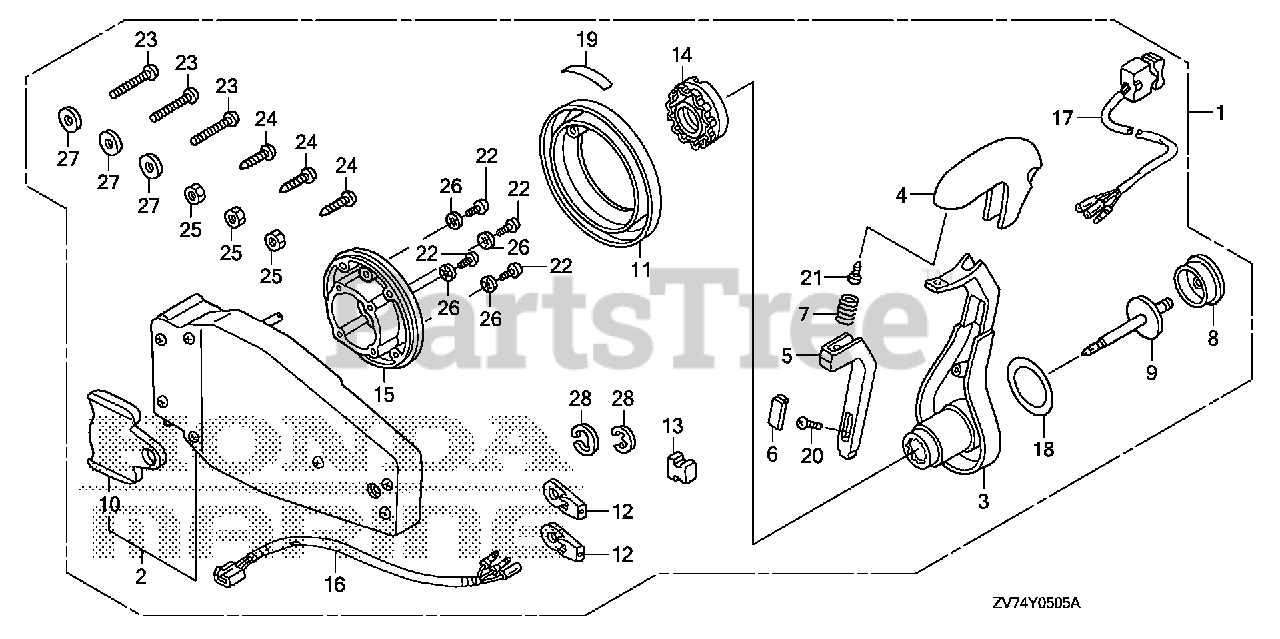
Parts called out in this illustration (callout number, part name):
1	BOX KIT, REMOTE CONTROL (FLUSH MOUNT)(L)
2	HOUSING ASSY., L. (INNER) (FLUSH MOUNT)
3	HANDLE, REMOTE CONTROL
4	COVER, GRIP
5	ARM, NEUTRAL LOCK
6	COVER, LOCK ARM
7	SPRING, NEUTRAL LOCK ARM
8	BUTTON, THROTTLE
9	SHAFT, THROTTLE BUTTON
10	PLATE, DWELL
11	COVER ASSY.
12	TERMINAL, CABLE
13	SPACER, CABLE CLAMP
14	HOLDER, NEUTRAL LOCK
15	BASE
16	SUB-HARNESS ASSY., POWER TRIM-TILT (C)
17	SWITCH ASSY., POWER TRIM-TILT (C)
18	MARK, HANDLE FLUSH MOUNT
19	MARK, FLUSH MOUNT
20	SCREW, TRUSS (4X12)
21	SCREW, PAN (5X16)
21	SCREW, PAN (5X10)
22	SCREW, PAN (5X30)
23	SCREW, PAN (6X35)
24	SCREW, TAPPING (6X30)
25	NUT, HEX. (6MM)
26	WASHER, LOCK (5MM)
27	WASHER, PLAIN (6MM)
28	E-RING (6MM)
